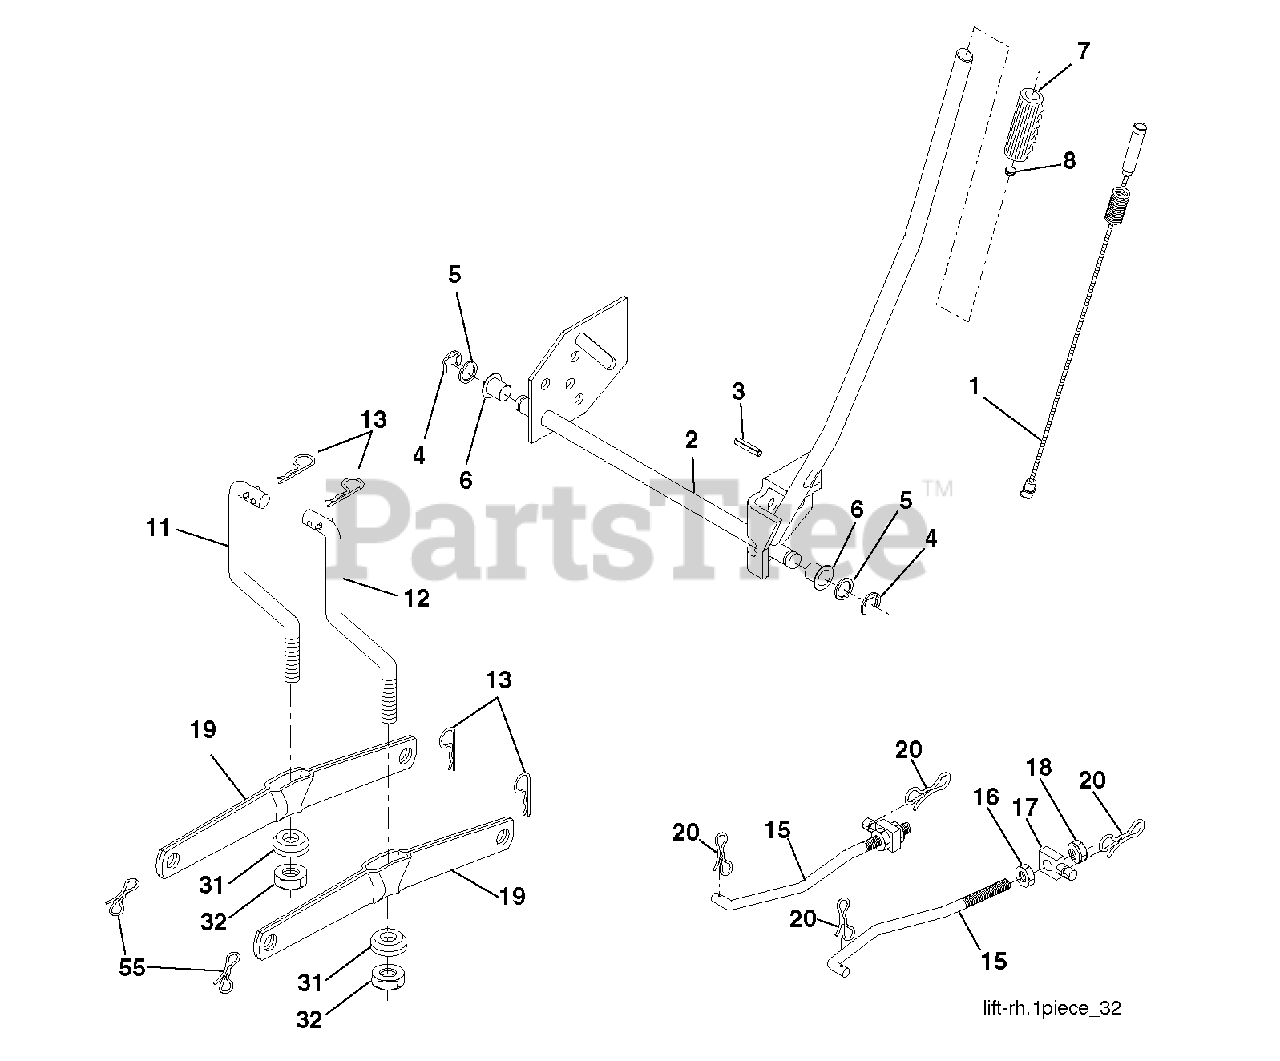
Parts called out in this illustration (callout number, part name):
1	PLUNGER.ASM.LIFT.LVR.BLK.17.32
2	SHAFT ASM R HANDLE
4	RETAINING RING LT
6	BEARING.NYLON
7	GRIP
8	PLUNGER BUT KIT
11	LINK LIFT LH
12	LINK LIFT RH
13	RETAINER-SPRNG RB
15	LINK.SUSPENSION.FRONT
16	NUT
18	NUT
19	ARM.REAR.SUSPENSION
20	PIN.COTTER.7/16.BOW TI
31	BEARING.PIVOT.LIFT
32	NUT CROWNLOCK 3/8-24
55	PIN.COTTER.5/16.BOW TI
